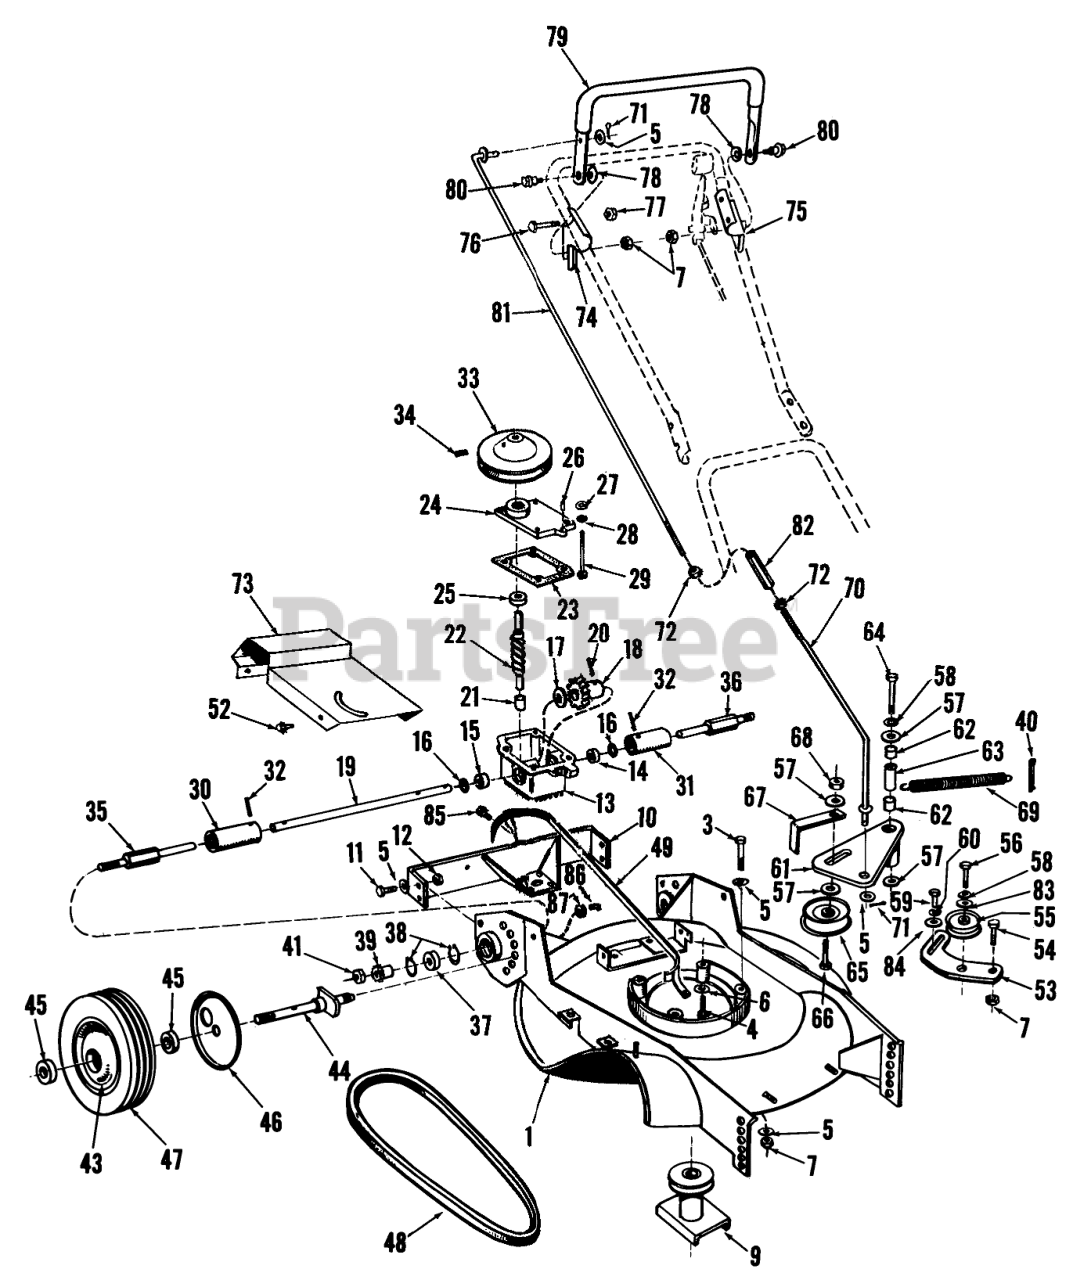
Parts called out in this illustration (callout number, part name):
1	Housing
3	SCREW-HH
4	SCREW-HH
5	WASHER-PLAIN
6	WASHER-LOCK
7	NUT-LOCK, NI
9	Blade Retainer
11	SCREW-HH
12	NUT-LOCK, NI
14	Bushing
15	Bushing
16	Seal
17	THRUST WASHER
18	WORM GEAR
20	PIN-SPRING
21	.437 NEEDLE BEARING
22	Worm Shaft
23	GASKET
24	Cover Gear Box
25	Bearing
26	3/16 X 1/2 ROLL PIN
27	WASHER-FLAT
28	WASHER-LOCK
29	SCREW-HH
30	Clutch Assembly
31	Clutch Assembly
32	PIN-ROLL
33	Pulley Gear Box
34	SCREW-HSH
35	OUTPUT SHAFT
36	OUTPUT SHAFT
38	1-1/8X056 IN SNP RING
41	NUT-HJ
45	BEARING-BALL
46	WHEEL COVER
48	V-BELT
49	Belt Guide
53	Arm, Auxiliary Idler
54	SCREW-HH
55	PULLEY-IDLER
56	SCREW-HH
57	WASHER-FLAT
58	WASHER-LOCK
59	SCREW-HH
60	WASHER-LOCK, INTERNAL
61	Idler Arm (Incl.(1) Ref.62)
62	BUSHING
63	ROLLED SPACER
64	SCREW-HH
65	IDLER PULLEY R
66	SCREW-HH
68	NUT-HEX
70	CONTROL ROD
71	PIN-COTTER
72	NUT-KEPS
73	Shroud
76	10-24X1-1/4 PAN HD MS
77	NUT-LOCK, NI
78	WASHER-SPRING
79	Control Bail
80	Screw
81	Control Rod
82	CONTROL ROD SLEEVE
